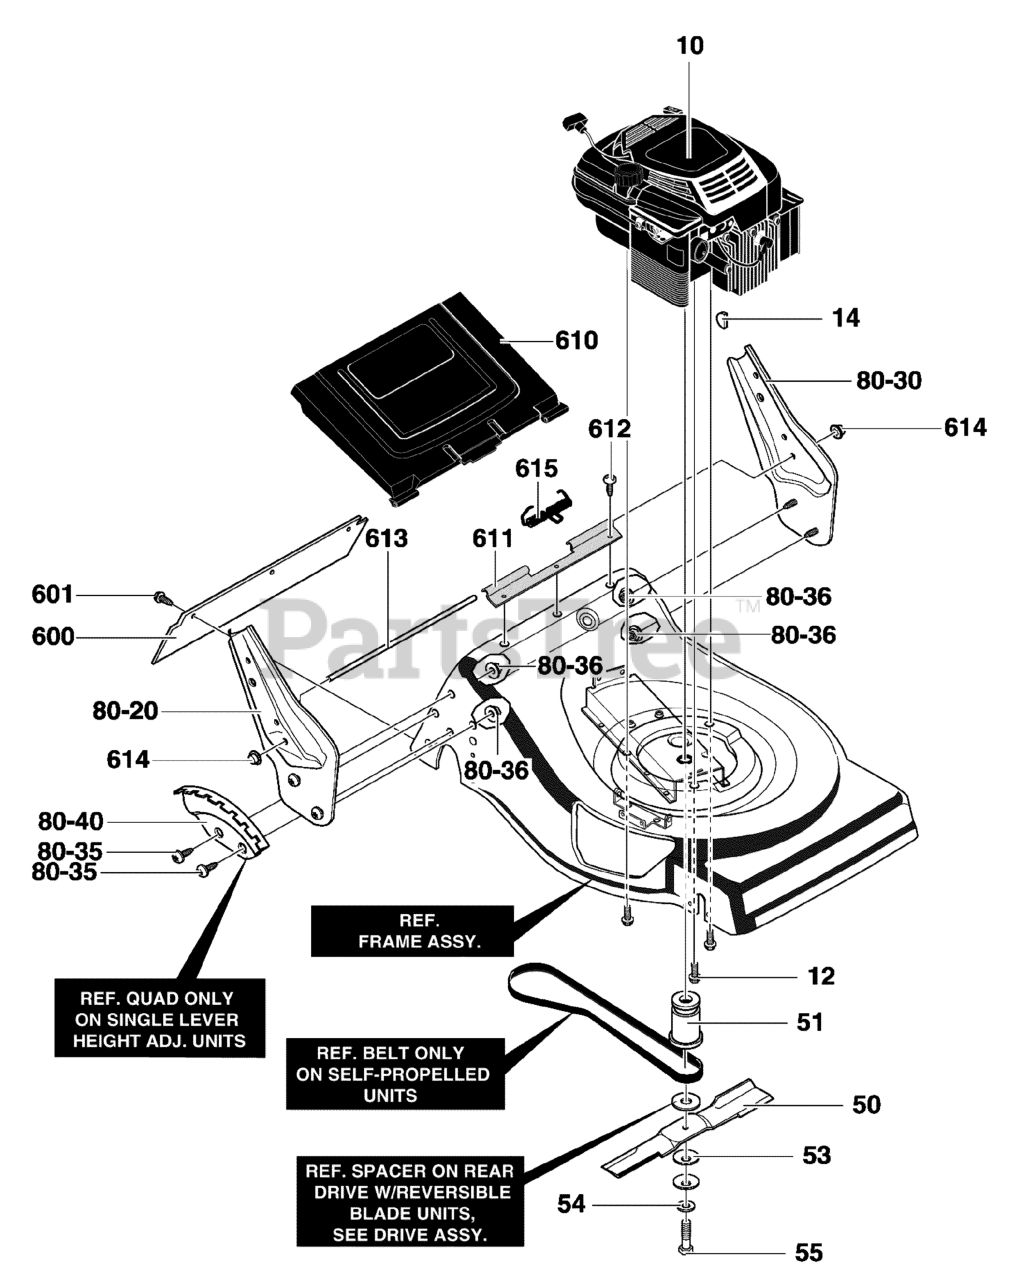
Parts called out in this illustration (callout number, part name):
10	ENGINE **
12	SCREW
14	WOODRUFF KEY 505
50	BLADE, 21" REVERSIBLE
51	ADAPTER, BLADE 21"
53	WASHER, BEVELLE
54	WASHER
55	SCREW, 3/8-24 x 2.00
80-20	BRACKET, HANDLE RH
80-30	BRACKET, HANDLE LH
80-35	SCREW, 5/16-18 x 0.75
80-36	NUT, 5/16-16
80-40	QUADRANT, HEIGHT ADJ
600	DEFLECTOR, REAR
601	SCREW, 10-16X.50
610	DOOR, REAR 21
611	SPACER
612	SCREW, 10-16X.50
613	ROD, PIVOT
614	CAP, PUSH ON
615	SPRING, TORSION
